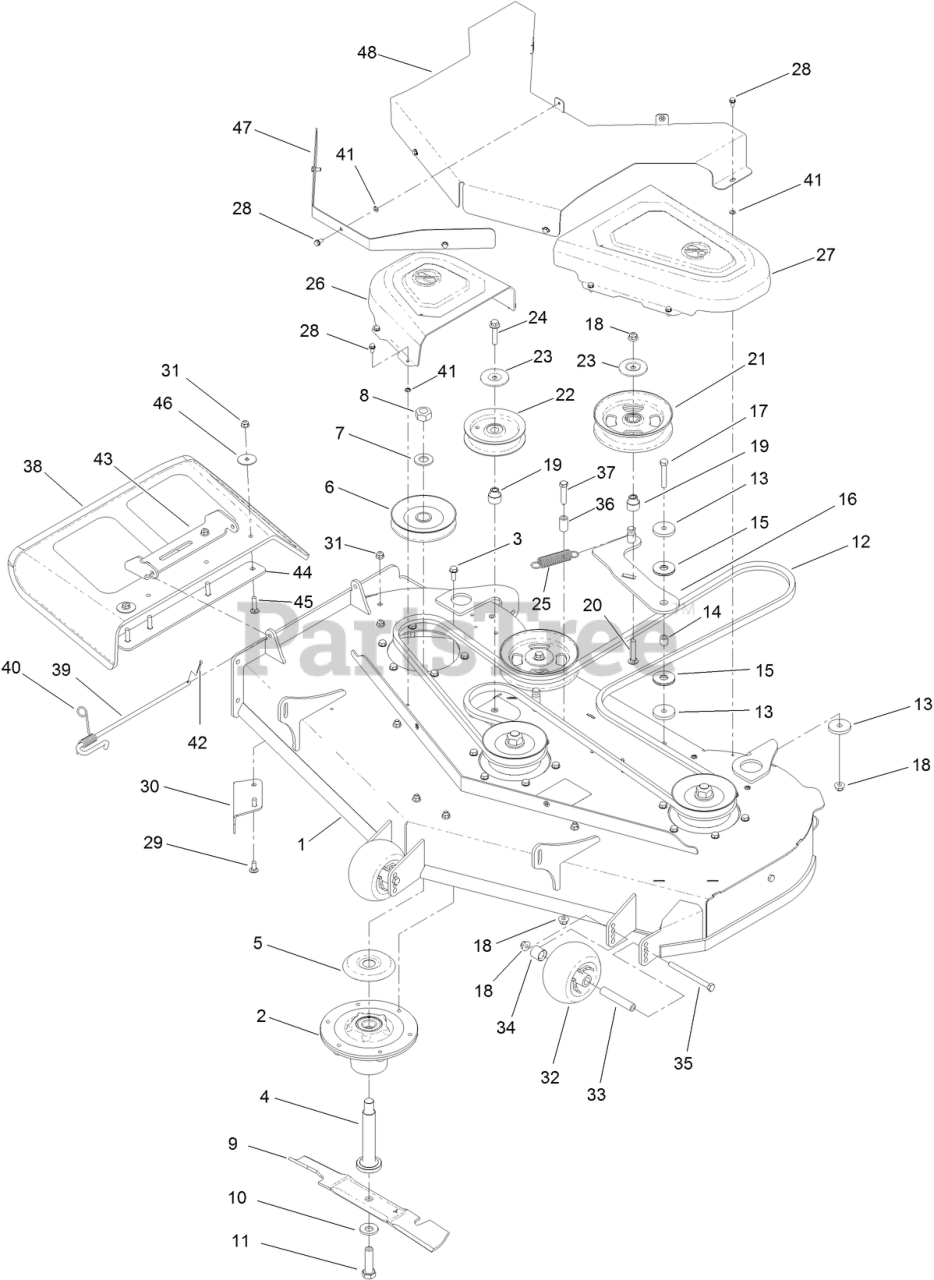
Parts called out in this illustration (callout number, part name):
1	DECK ASM-48"
2	SPINDLE ASM
3	SCREW-TAPTITE
4	SHAFT-SPINDLE
5	SHIELD-BEARING
6	PULLEY
7	WASHER
8	NUT-HEX
9	BLADE - HI FLOW, 16.50 IN
10	WASHER-BELLEVILLE
11	SCREW-BLADE
12	BELT, DECK
13	WASHER-PLAIN
14	BUSHING-IDLER
15	WASHER-FRICTION, COMPOSITE
16	IDLER ARM ASM
17	SCREW-HH
18	NUT-HF, NI
19	BUSHING-IDLER
20	SCREW-CARR
21	PULLEY-IDLER, FLAT
22	PULLEY-IDLER, FLAT
23	SHIELD-DUST
24	SCREW-HHF
25	SPRING-EXTENSION
26	COVER-BELT, RH
27	COVER-BELT, LH
28	SCREW-HWH
29	SCREW-CARR
30	BAFFLE-CUTOFF
31	NUT-HF, NI
32	ROLLER-SCALP, ANTI
33	TUBE-SPANNER
34	SPACER-AXLE, REAR
35	SCREW-HH
36	SPACER-FENDER
37	SCREW-HH
38	DEFLECTOR
39	PIN-CHUTE
40	SPRING-TORSION
41	NUT-RETAINING
42	PIN-COTTER
43	BRACKET UPPER, DEFLECTOR
44	PLATE-DEFLECTOR
45	SCREW-CARR
46	WASHER-FLAT
47	PLATE-GUARD
48	PLATE-GUARD, CENTER
